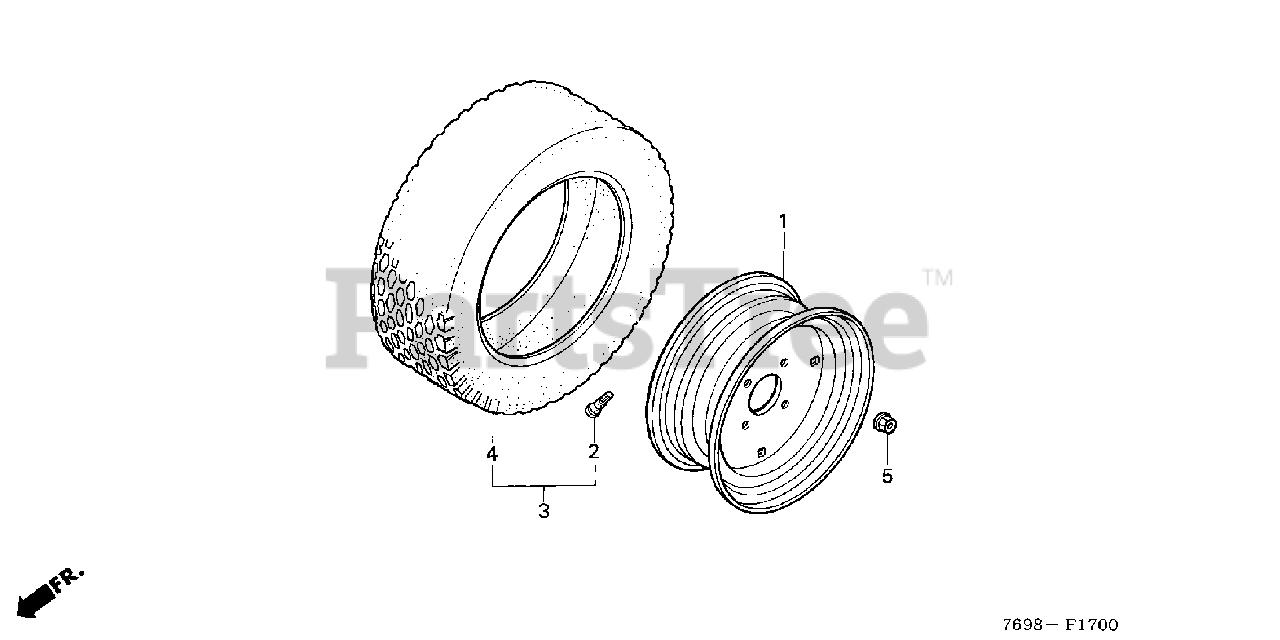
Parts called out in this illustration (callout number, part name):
1	WHEEL (5JAX12WDC) *NH35M* (CLOUD SILVER METALLIC)
1	WHEEL (12X4JA) (WDC)
2	VALVE, RIM
3	TIRE ASSY., FR. (20X7.00-12) (2PR)
4	TIRE, FR. TUBELESS (5-12-4PR)
5	NUT, WHEEL (12MM)
